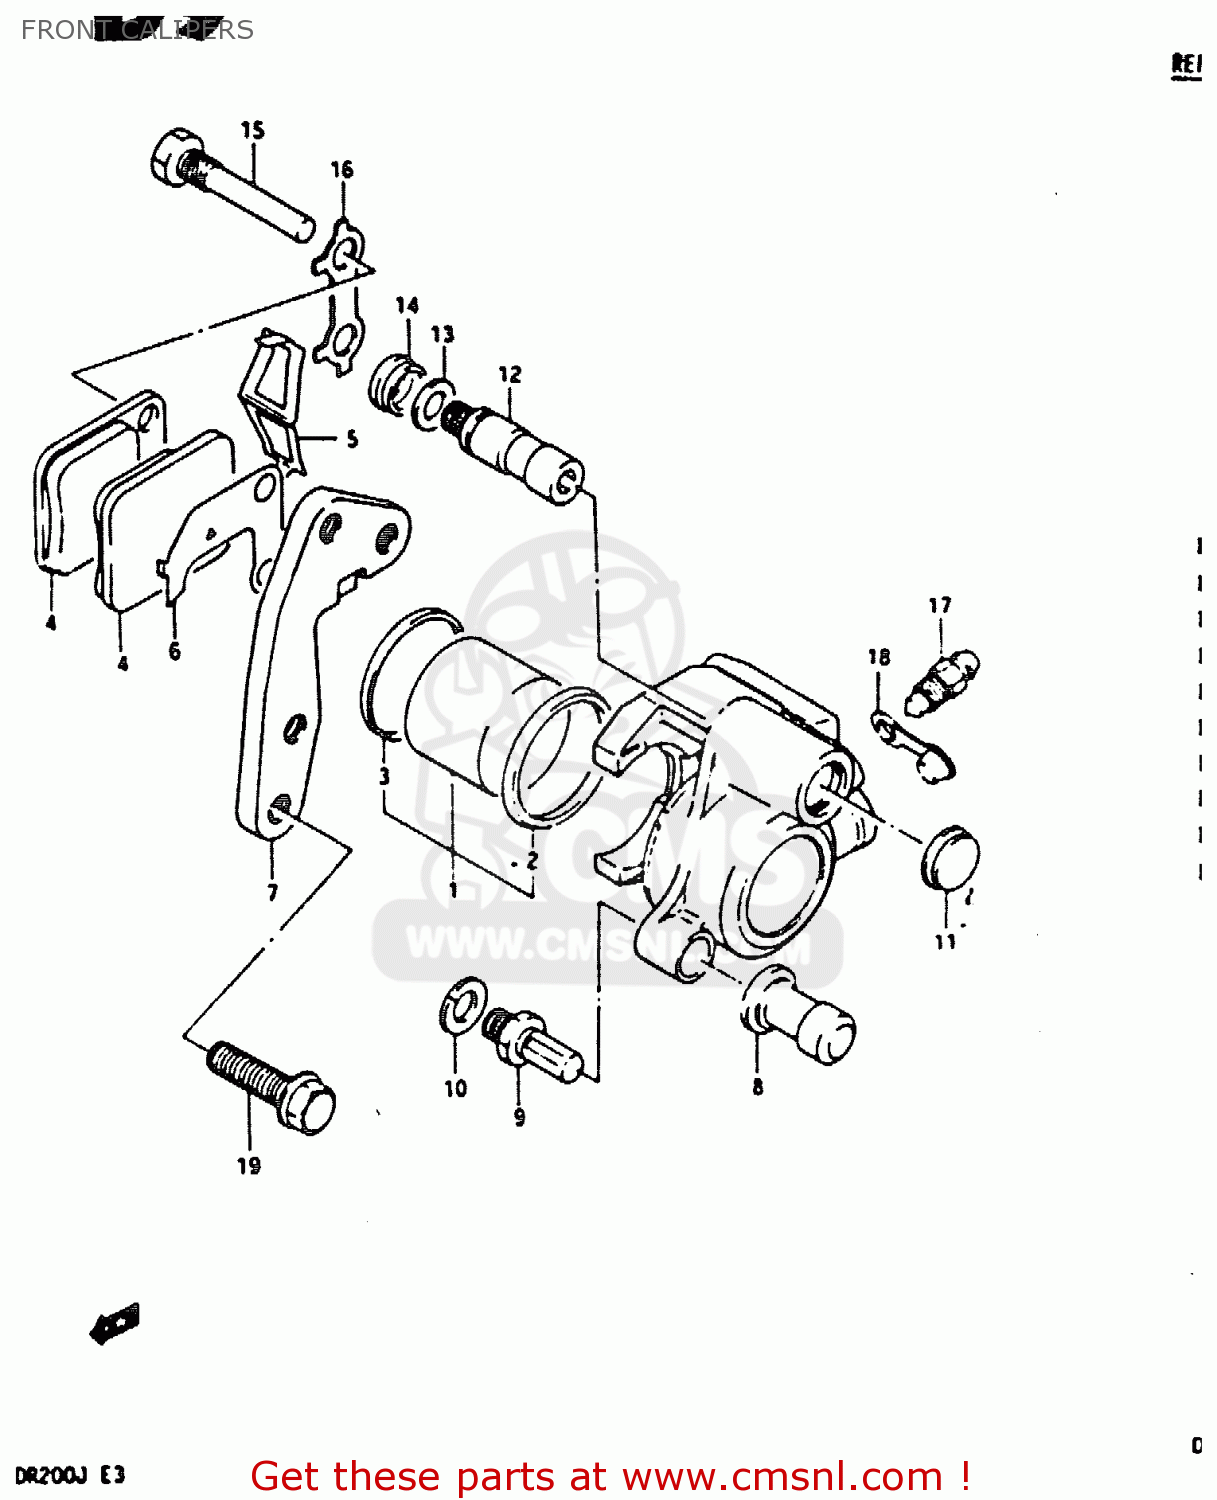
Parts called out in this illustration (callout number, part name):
1	PISTON SET,CALIPERS
2	SEAL,PISTON
3	BOOT,PISTON
4	PAD
5	SPRING,PAD
6	SHIM
7	BRACKET
8	BOOT
9	BOLT,PIN
10	WASHER,WAVE
11	DUST SEAL
12	PIN,SLIDE
13	SPRING,FRICTION
14	BOOT,PIN
15	PIN,HANGER
16	WASHER
17	BLEEDER
18	CAP,BLEEDER
19	BOLT 8X30
